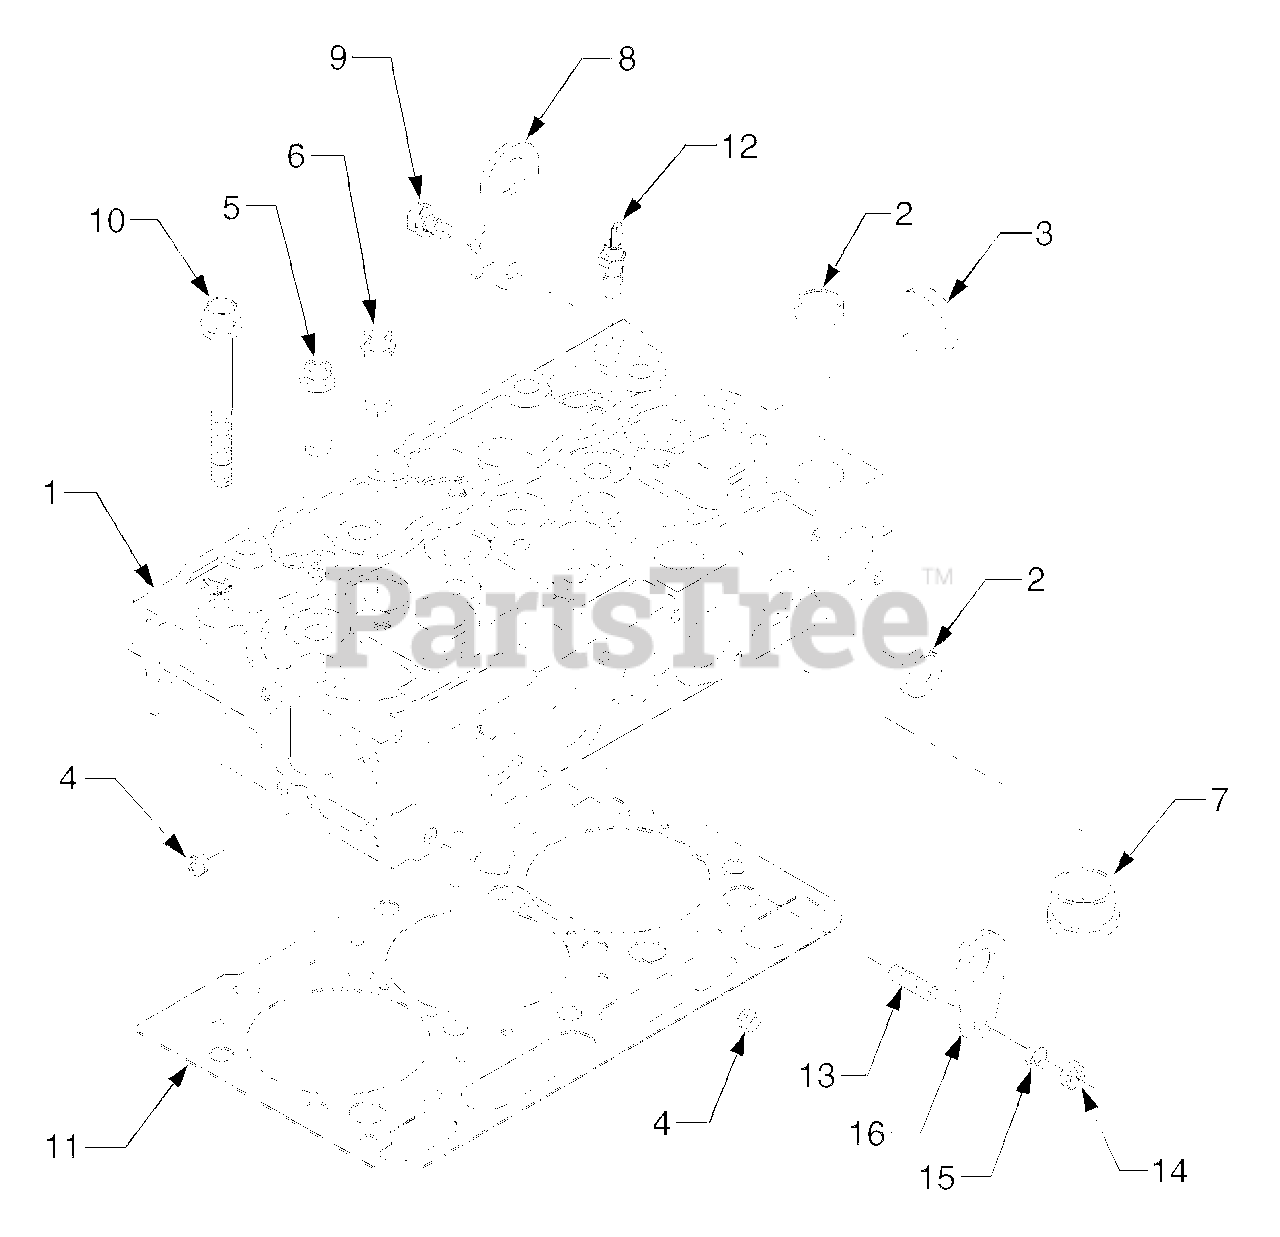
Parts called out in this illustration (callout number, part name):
1	Cylinder Head Ass'y
5	Guide, Inlet Valve
6	Guide, Outlet Valve
10	Bolt, Cylinder Head
11	Gasket, Cylinder Head
12	Switch, Thermostat
15	Washer, Spring
